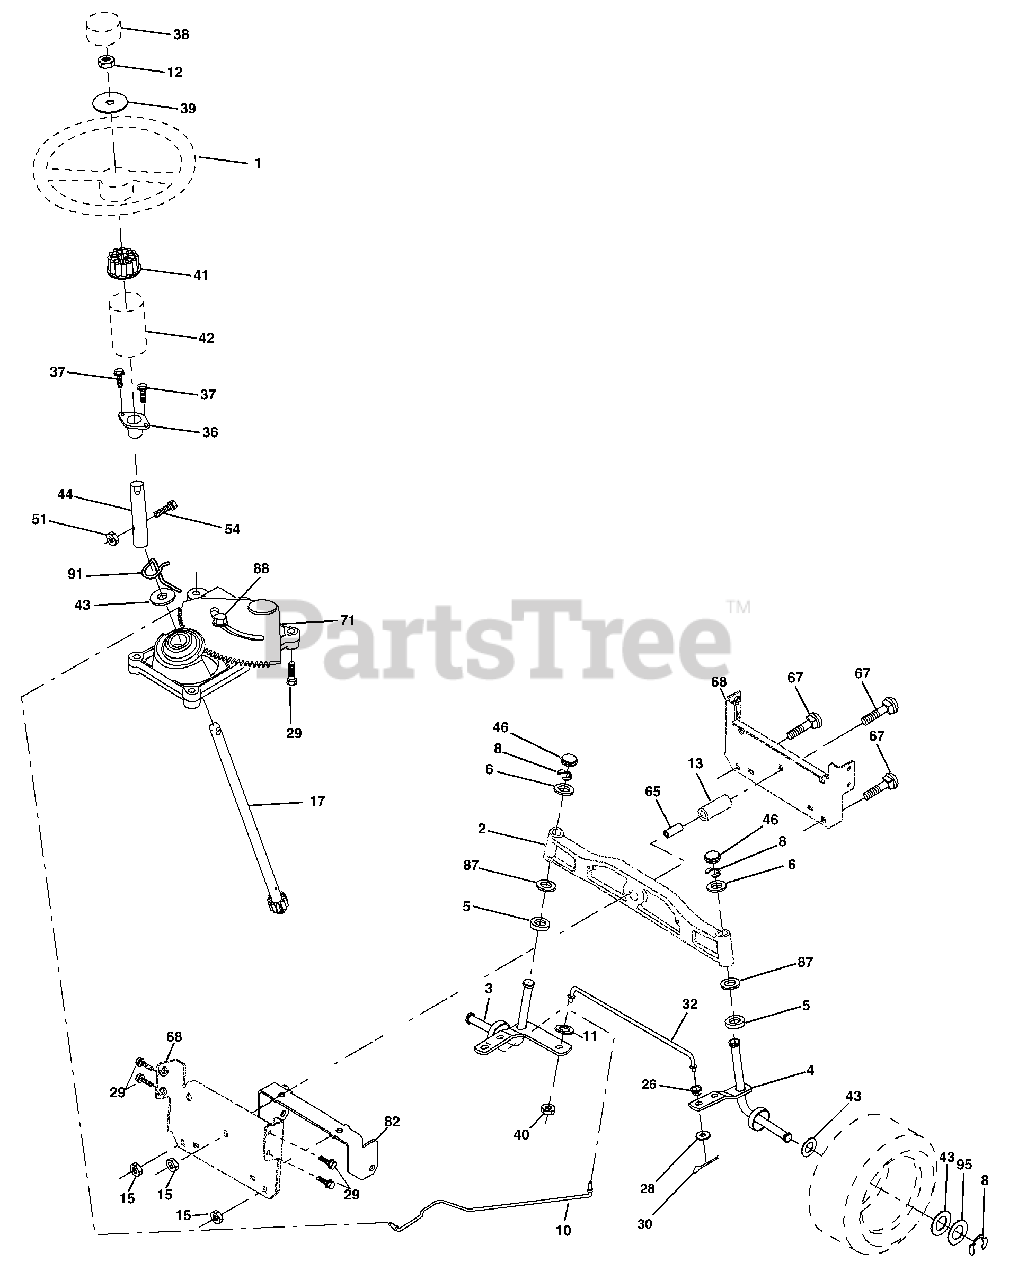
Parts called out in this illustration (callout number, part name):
1	Steering Wheel
2	Axle Assembly
3	Spindle Assembly, L.H.
4	Spindle Assembly, R.H.
5	Bearing, Race, Thrust, Hardened
6	Washer 25/32 x 1-5/8 x 16 Ga.
8	Ring, Klip
10	Draglink
11	Washer, Lock
12	Nut Hex Jam Toplock 1/2-20 Unf
13	Spacer Bearing Axle Front
15	Nut, Hex Flange Lock
17	Shaft Assembly, Steering
26	Bushing, Link, Drag
28	Washer 13/32 x 7/8 x 16 Ga.
29	Screw 3/8-16 x 3/4
30	Pin Cotter
32	Rod, Tie
36	Bushing, Steering
37	Screw
38	Insert, Steering Wheel
39	Washer 9/16 x 1-1/2 11 Ga.
40	Nut Crownlock 3/8-24
41	Adaptor, Steering Wheel
42	Boot, Steering Shaft
43	Washer 25/32 x 1-1/4 x 16 Ga.
44	Extension Shaft Steering
46	Cap, Spindle
51	Nut Crownlock 1/4-28
54	Bolt Hex 1/4-28 UNF x 1-1/4 Gr. 8
65	Spacer Brace Axle
67	Bolt RDHD Sqnk 3/8-16 x 2-1/4
68	Axle, Brace
71	Steering Asm.
82	Bracket Susp. Chassis Front
87	Washer Flat
88	Bolt Shoulder 7/16-20 Unc
91	Clip Steering
95	Washer Hardened
